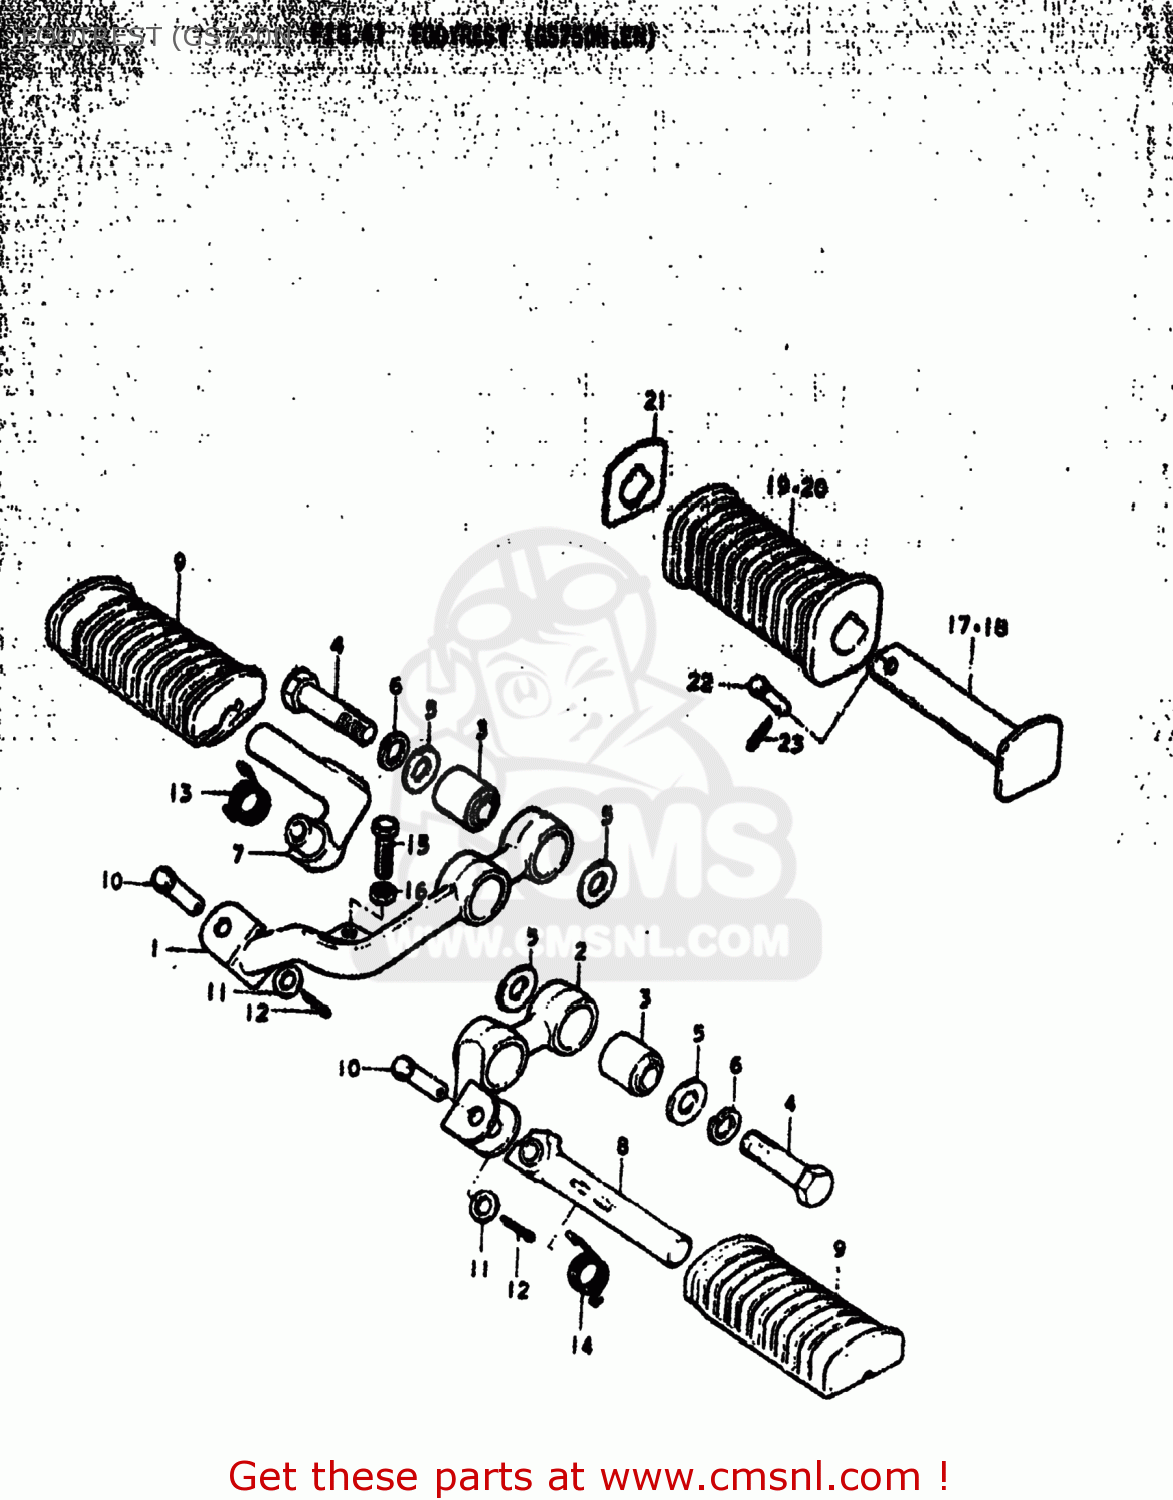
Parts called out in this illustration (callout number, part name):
1	BAR,FRONT FOOTREST
2	BAR,FRONT FOOTREST,LEFT
3	BUSH
4	BOLT
5	WASHER (10.1X21X2.3)
6	LOCK WASHER
7	BAR,FRONT FOOTREST,RIGHT NO
8	BAR,FRONT FOOTREST,LEFT NO
9	RUBBER,FR FOOTREST
10	PIN
11	WASHER
12	PIN 20X20
13	SPRING
14	SPRING
15	BOLT
16	NUT 6MM
17	BAR,REAR FOOTREST
18	BAR,REAR FOOTREST
19	RUBBER,PILLION FOOTREST
20	RUBBER, LH
21	WASHER,REAR FOOTREST RUBBER
22	PIN
23	PIN 20X20
